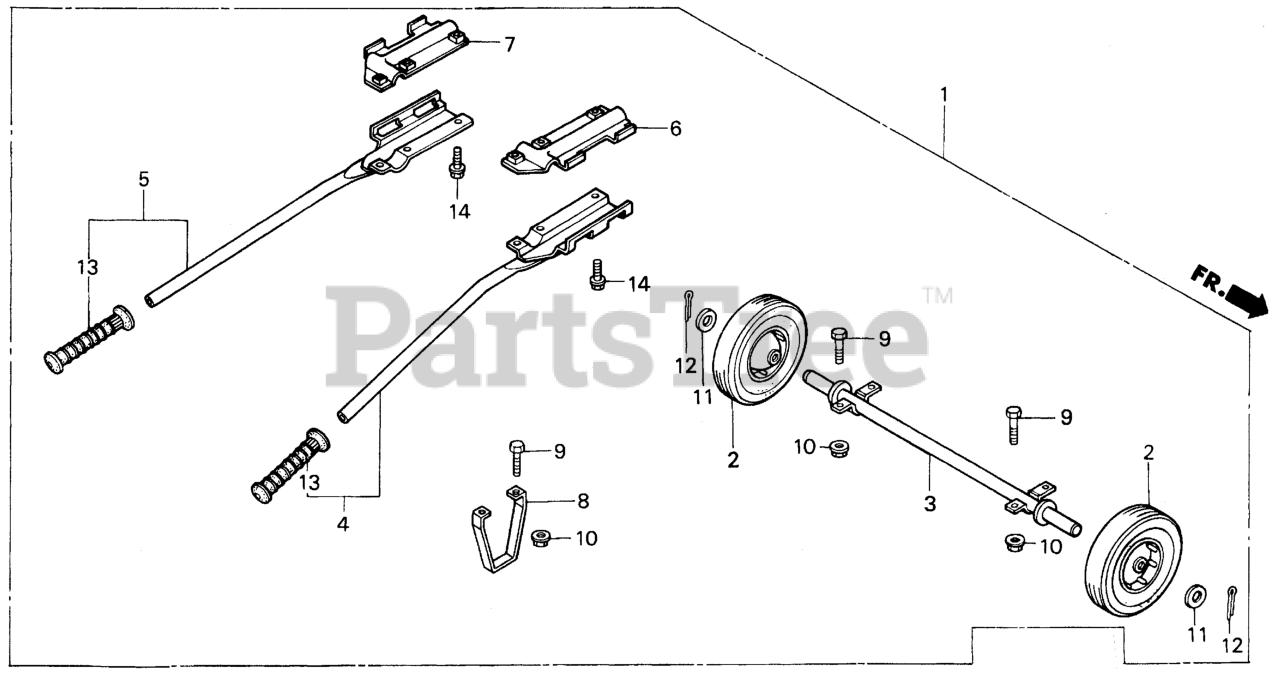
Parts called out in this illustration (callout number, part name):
1	WHEEL KIT (2-WHEELS)
2	WHEEL (GLEASON 10"X2.75"=254X70)
3	SHAFT, WHEEL
4	HANDLE, R. (LOWER)
5	HANDLE, L. (LOWER)
6	BRACKET, R. HANDLE (UPPER)
7	BRACKET, L. HANDLE (UPPER)
8	STAND
9	BOLT, HEX. (8X16)
10	NUT, FLANGE (8MM)
11	WASHER, PLAIN (20MM)
12	PIN, SPLIT (4.0X28)
12	PIN, COTTER (4.0X30)
13	GRIP D, R. HANDLE (BOTH SIDES)
14	BOLT, FLANGE (8X16) Use from Engine SN 1000016.
